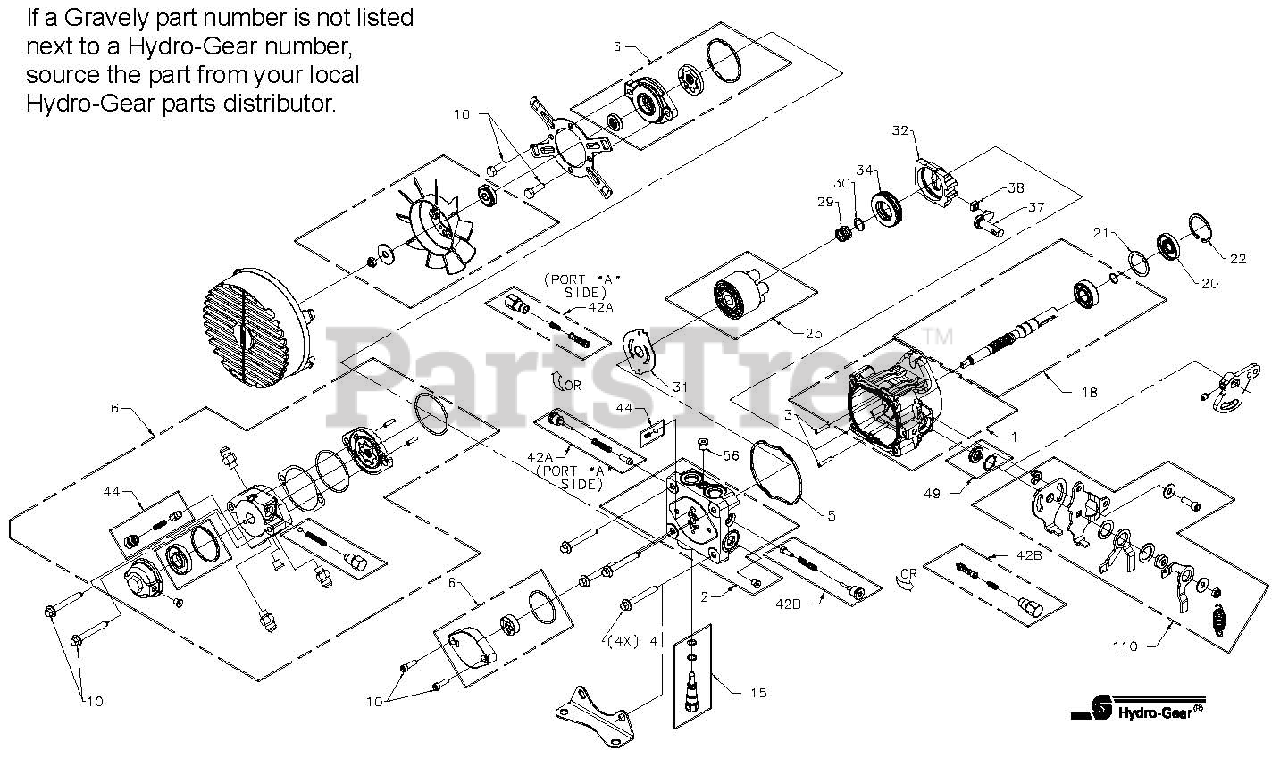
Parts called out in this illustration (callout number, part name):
1	Kit, Housing
2	Kit, End Cap w/Poppets
3	Straight Headless Pin
4	Hex, Flange Bolt M8-1.25 x 60mm
5	Housing O-Ring
6	Kit, Chg Pump
10	Cap Screw 5/16-18
15	Kit, Bypass
18	Kit, Pump Shaft (15mm Straight Keyed, Thru)
20	Lip Seal 17 x 40 x 7 PTC
21	Spacer
22	Retaining Ring
25	Cylinder Block Kit
29	Block Spring
30	Block Thrust Washer
31	Valve Plate
32	Swashplate
34	Ball Thrust Bearing
37	Arm, Trunnion, Tapered Square
38	Slot Guide
42	Kit, Shock Valve (200 Bar .031 Orifice)
44	Kit, Charge Relief Valve
49	Trunnion Seal - Retainer Kit
56	Plug, Straight Thread
110	Kit, Return
NS	Overhaul Seal Kit
